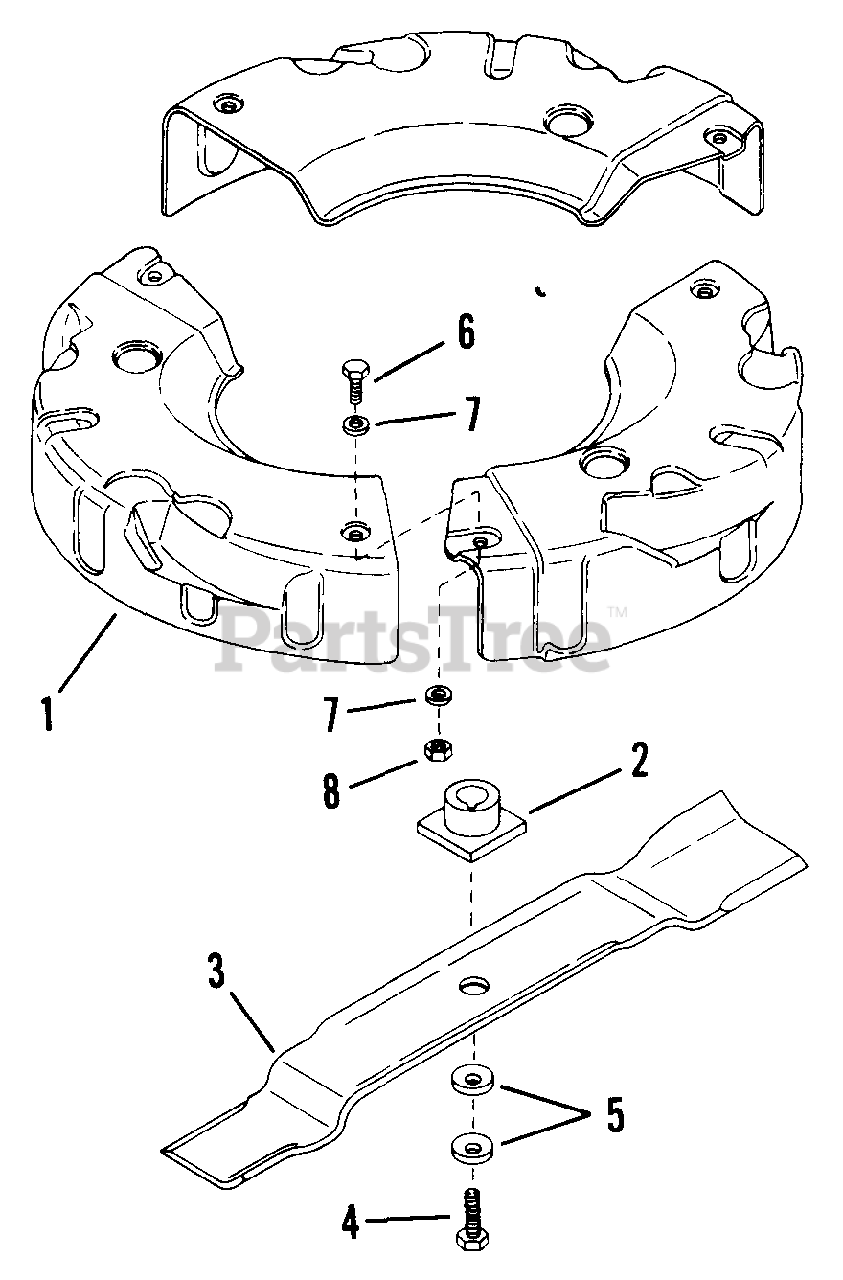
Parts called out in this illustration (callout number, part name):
2	HUB, 7/8" I.D.
2	HUB (25mm I.D.)
3	BLADE, Mulcherizer
4	SCREW, 3/8-24 x 1 3/4" Hex Head Cap (Gr.5)
5	WASHER, Cone
6	SCREW, 1/4-28 x 5/8" Hex Head Cap (Gr.5)
7	WASHER, 1/4 Flat
8	NUT, 1/4-28 Hex Lock
